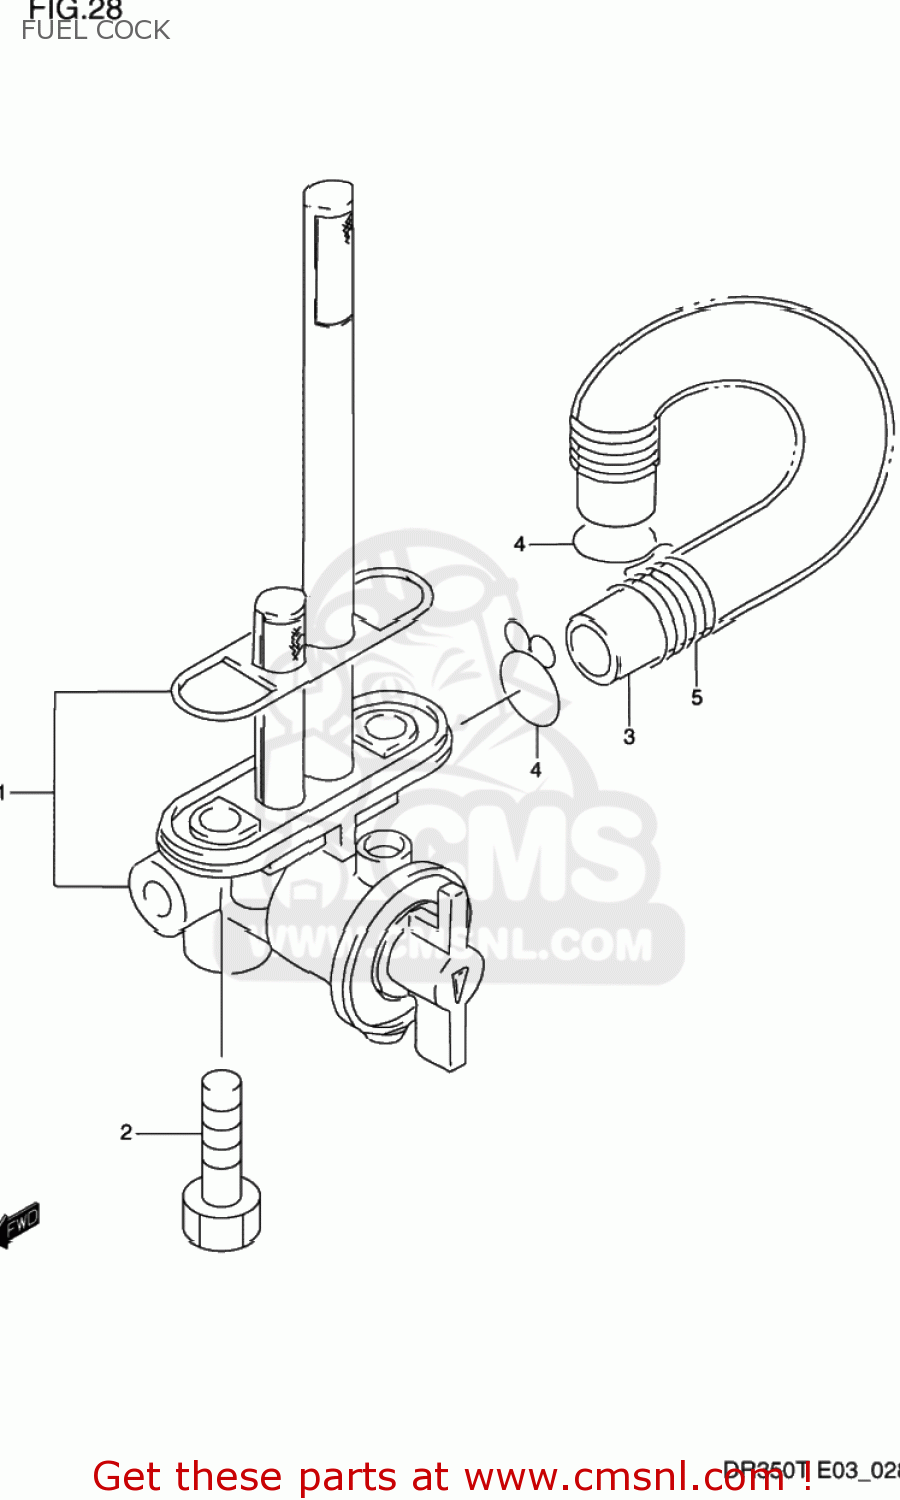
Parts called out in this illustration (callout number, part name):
1	COCK ASSY,FUEL
2	SCREW
3	HOSE(7X10.2X600)
4	CLIP
5	SPRING
